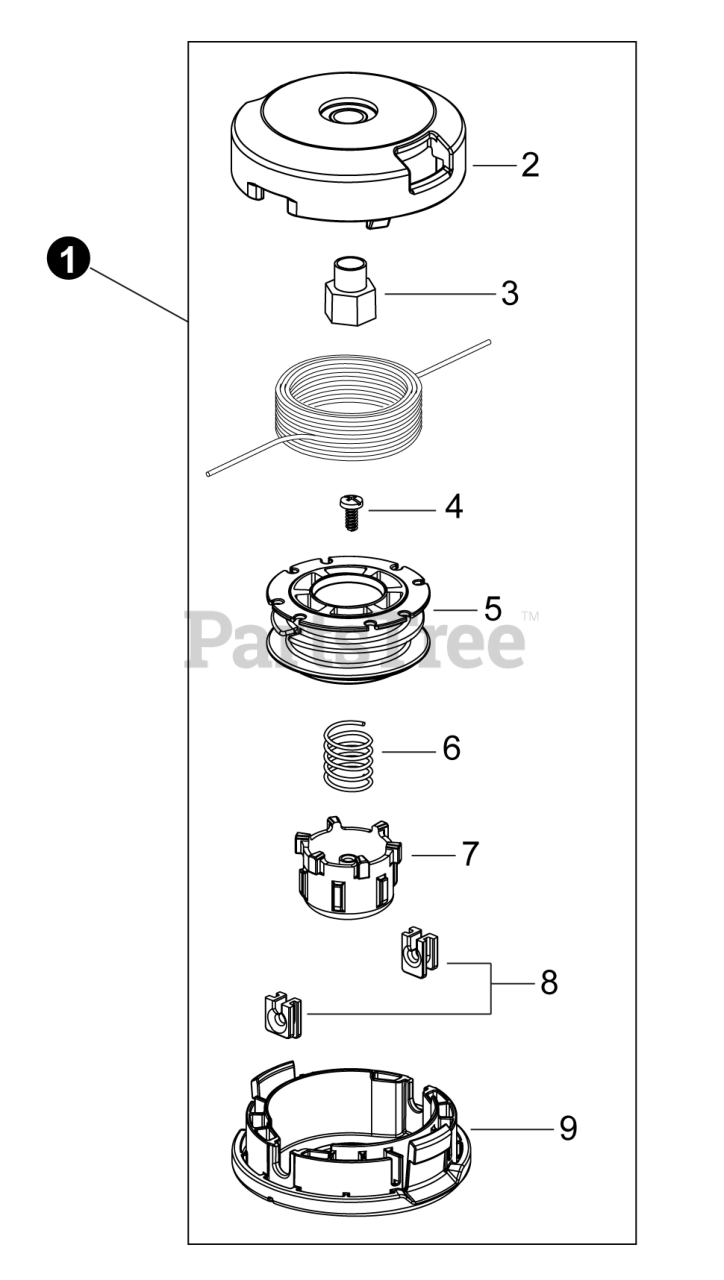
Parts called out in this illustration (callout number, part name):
1	TRIMMER HEAD G137
2	COVER, SPOOL
3	BUSHING
9	HOUSING, SPOOL
